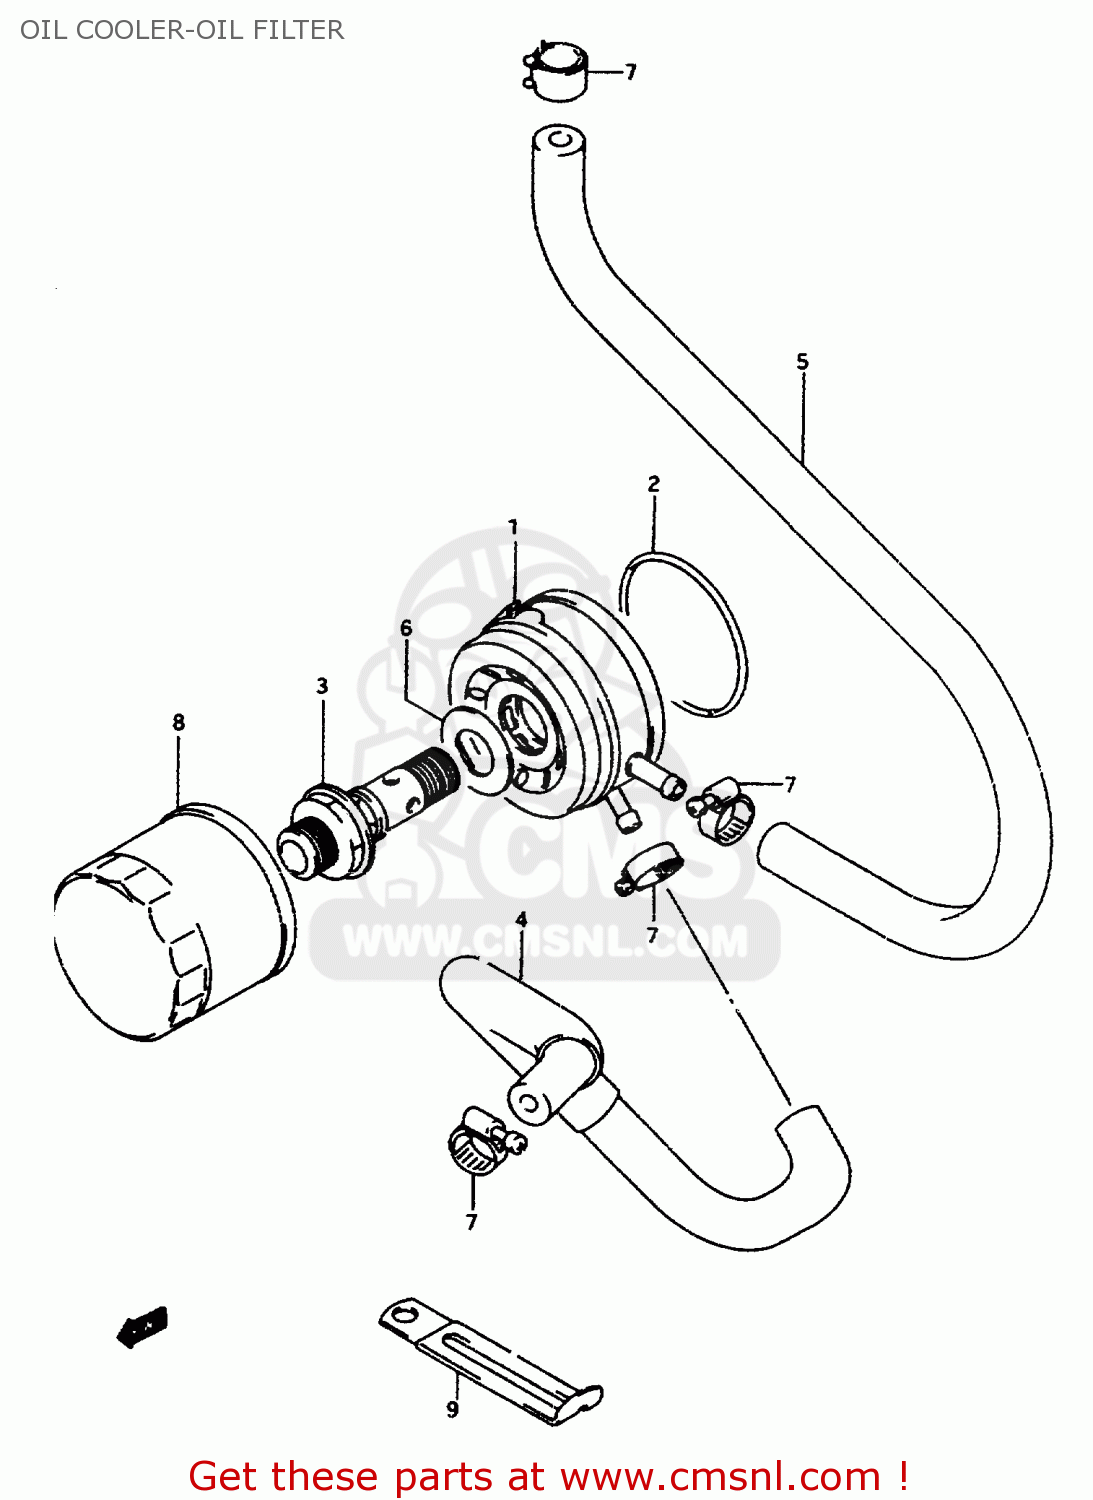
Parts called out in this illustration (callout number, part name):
1	COOLER ASSY,OIL
2	O RING(D:3.1,ID:63.9)
3	BOLT,OIL COOLER UNION
4	HOSE,OIL COOLER WATER IN
5	HOSE,OIL
6	SHIM
7	CLIP
8	FILTER ASSEMBLY,ENGINE OIL
9	CLAMP
